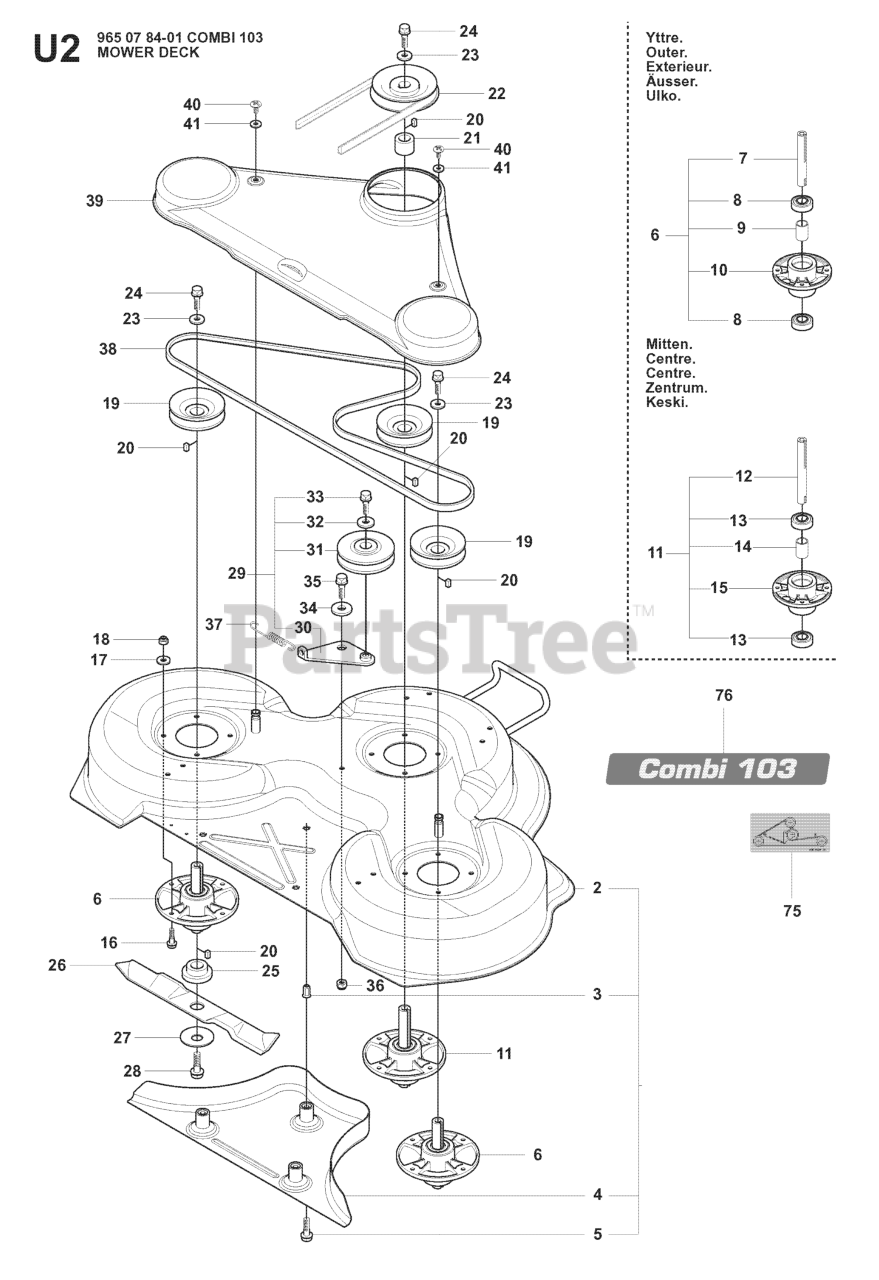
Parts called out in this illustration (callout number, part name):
1	CUTTING DECK
2	CUTTING DECK ASSY
6	RP SPINDLE ASSY
10	BEARING HOUSING
11	SPINDLE ASSY
15	BEARING HOUSING
17	WASHER BRB 8.4X17
18	LOCKNUT M8
27	WASHER
29	BELT TENSIONER ASSY
30	BELT TENSIONING ARM
34	WASHER
36	LOCKNUT M8
